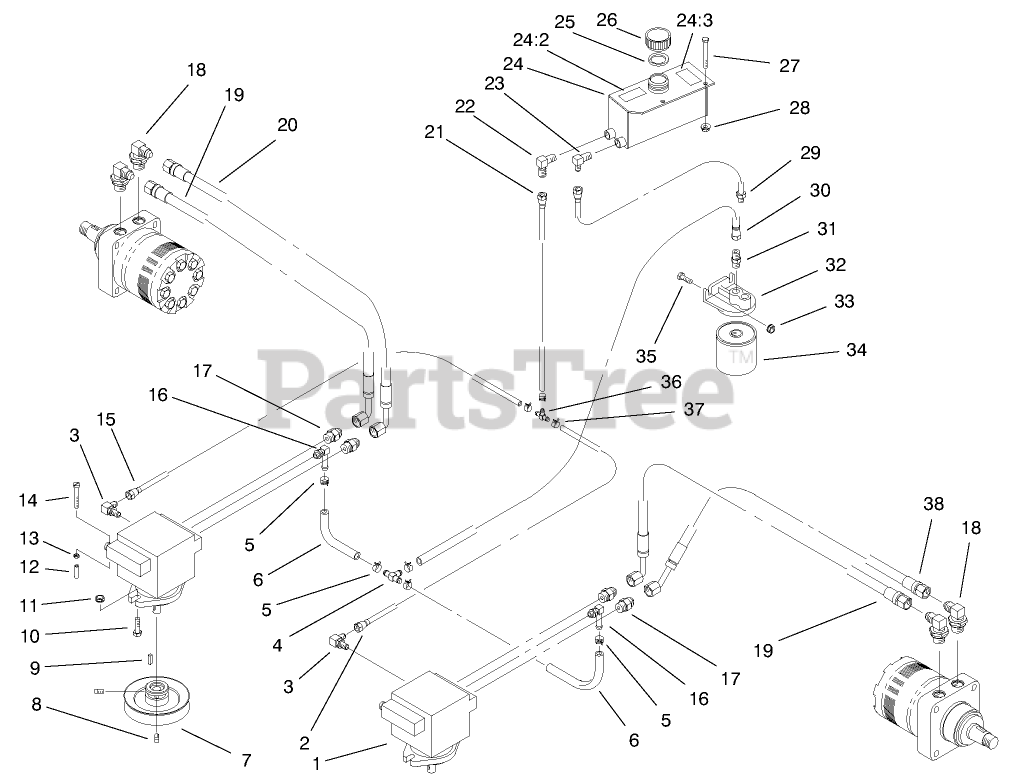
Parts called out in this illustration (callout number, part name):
1	Pump-Hydro
2	Hose-Low Pressure
3	Elbow
4	Fitting
5	Clamp-Hose
6	Hose-Low Pressure
7	Sheave w/Hub
8	SCREW-SET, SQH
9	Key
10	SCREW-HH
11	NUT-HHF, WHIZ
12	Grip
13	NUT-LOCK, NI
14	Screw-PPH
15	Hose-Low Pressure
16	Elbow
17	Adapter
18	Elbow 90
19	Hose
20	Hose
21	Hose
22	Elbow
23	Elbow
24	HYDRAULIC TANK ASM
24:2	DECAL-SURFACE, HOT
24:3	Decal-Hydraulic Tank
25	Gasket
26	Cap
27	SCREW-HH
28	NUT-HF
29	Hose
30	Hose
31	Connector
32	Head-Filter
33	NUT-HF
34	Filter-Hydro
34	Filter-Winter
35	SCREW-HH
36	Fitting
37	Clamp-Hose
38	Hose
39	DECAL-SURFACE, HOT
40	Decal-Hydraulic Tank
